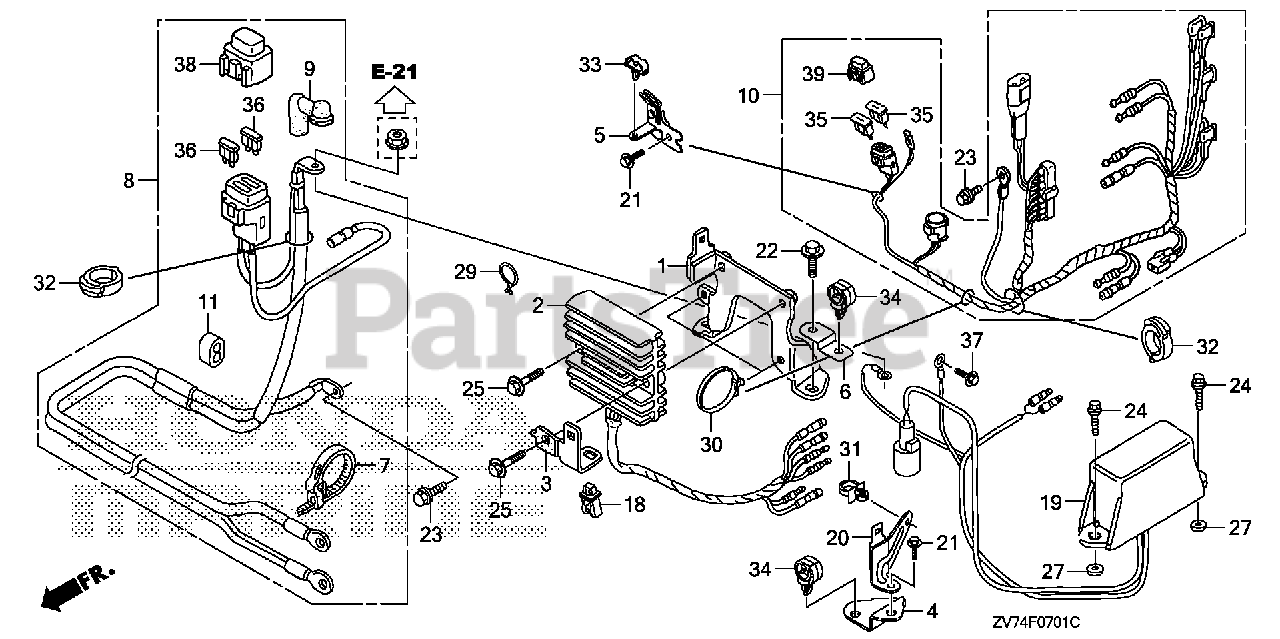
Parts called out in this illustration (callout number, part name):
1	BRACKET, REGULATOR
2	RECTIFIER ASSY., REGULATOR (12A)
3	BRACKET, CONNECTOR
5	BRACKET, FUSE CASE
7	BAND, WIRE
8	CABLE ASSY., STARTER
9	COVER, TERMINAL
10	CABLE ASSY., REMOTE CONTROL (A)
11	CLAMP, IGNITION WIRE
18	CLIP B, AIR TEMPERATURE SWITCH WIRE
21	BOLT, FLANGE (6X14) (CT200)
22	BOLT, FLANGE (6X12) (CT200)
23	BOLT, FLANGE (6X12) (CT200)
25	BOLT, FLANGE (6X20)
30	STRAP, CABLE (118MM) (BLACK)
32	CLIP, WIRE HARNESS
33	CLIP, CORD
35	FUSE, BLADE (10A)
36	FUSE, BLADE (15A)
38	COVER ASSY., FUSE (15A)
39	COVER ASSY., FUSE (10A)
